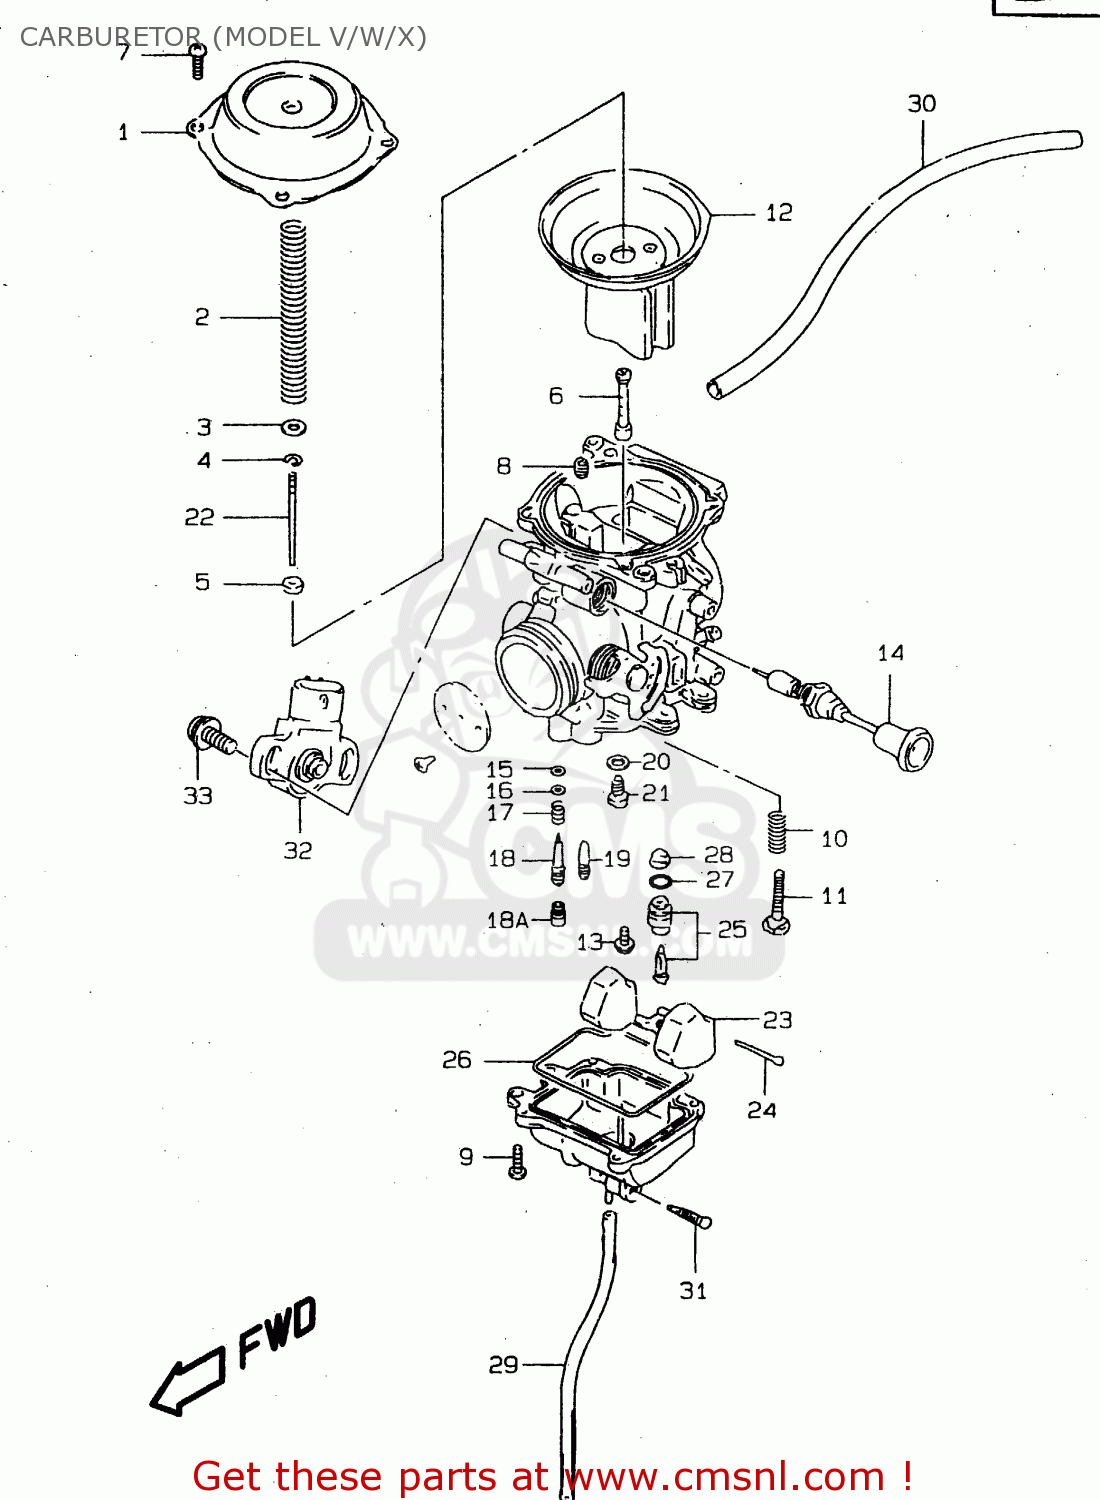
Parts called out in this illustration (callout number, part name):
1	COVER,DIAPHRAGM
2	SPRING
3	RING
4	CLIP
5	RING
6	JET,NEEDLE(P-5)
7	SCREW
8	JET,AIR(150)
9	SCREW
10	SPRING,THROTTLE SCREW
11	ADJUSTER
12	DIAPHRAGM ASSY
13	SCREW
14	PLUNGER ASSY
15	O RING,PILOT AIR SCREW
16	WASHER
17	SPRING
18	SCREW,PILOT
18A	PLUG
19	JET,PILOT(40)
20	WASHER
21	JET,MAIN(110)
22	NEEDLE,JET
23	FLOAT
24	PIN,FLOAT
25	VALVE ASSY,NEEDLE
26	O RING,FLOAT CHAMBER
27	O-RING,NEEDLE VALVE
28	FILTER
29	HOSE(3X5X650)
30	HOSE(5X8.2X600)
31	SCREW,DRAIN
32	SENSOR ASSY,THROTTLE
33	SCREW, SENSOR
